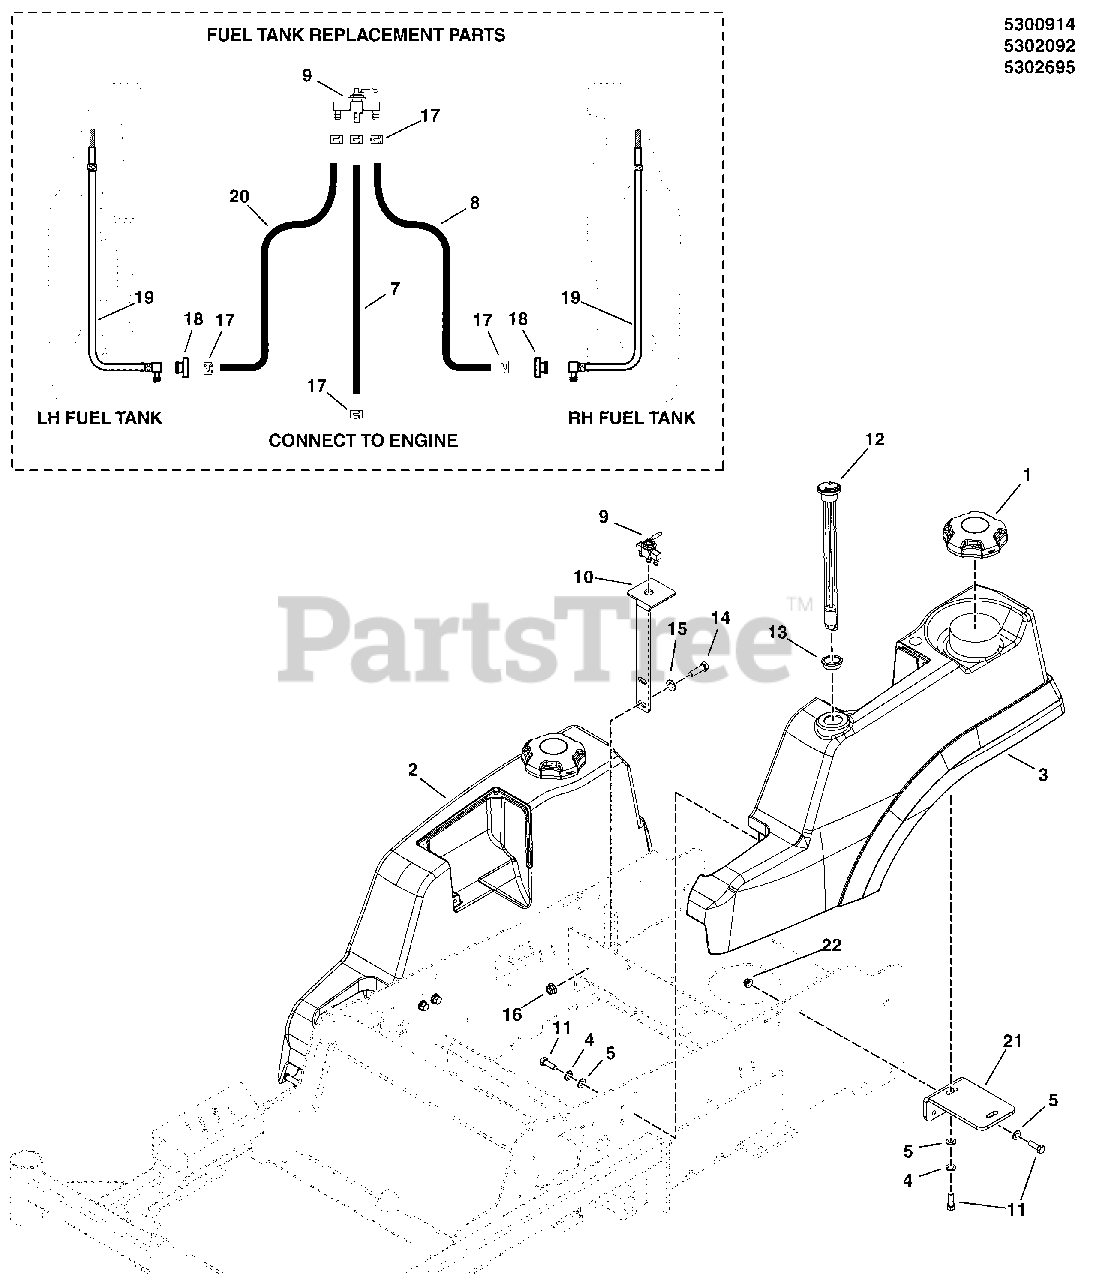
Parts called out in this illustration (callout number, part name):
1	FUEL CAP, 3-1/2", MANAGED VENT OUT, 12"
2	TANK, FUEL, SNAP & SNP PRO - RH
3	TANK, FUEL, SNAP & SNP PRO - LH
4	WASHER, 5/16 LOCK YZ
5	WASHER, 5/16" SAE
7	HOSE, FUEL, 1/4 IN, LW PRMTN, 6" LONG
8	HOSE, FUEL, 1/4 IN, LW PRMTN, 24" LONG
9	VALVE, FUEL, STR. OUTLET
10	BRACKET, FUEL VALVE, IS3000 - RED
11	BOLT, 5/16-18 X 1 GD5 YZ
12	FUEL GAUGE, 10" (SV)
13	GROMMET, FUEL GAUGE (SV)
14	BOLT, 3/8-16 X 1-1/2" GD5 CZ
15	WASHER, 3/8 SAE
16	NUT, 3/8-16 HEX NYLOCK FLANGE
17	CLAMP, HOSE, EXTERNAL, 1/2 - RED
18	KIT, BUSHING FUEL (SV)
19	PICKUP TUBE ASSEMBLY, FUEL LINE (SV)
20	HOSE, FUEL, 1/4 IN, LW PRMTN, 26" LONG
21	MOUNT, TANK, REAR - RED
22	NUT, 5/16-18 HEX NYLOCK FLANGE
